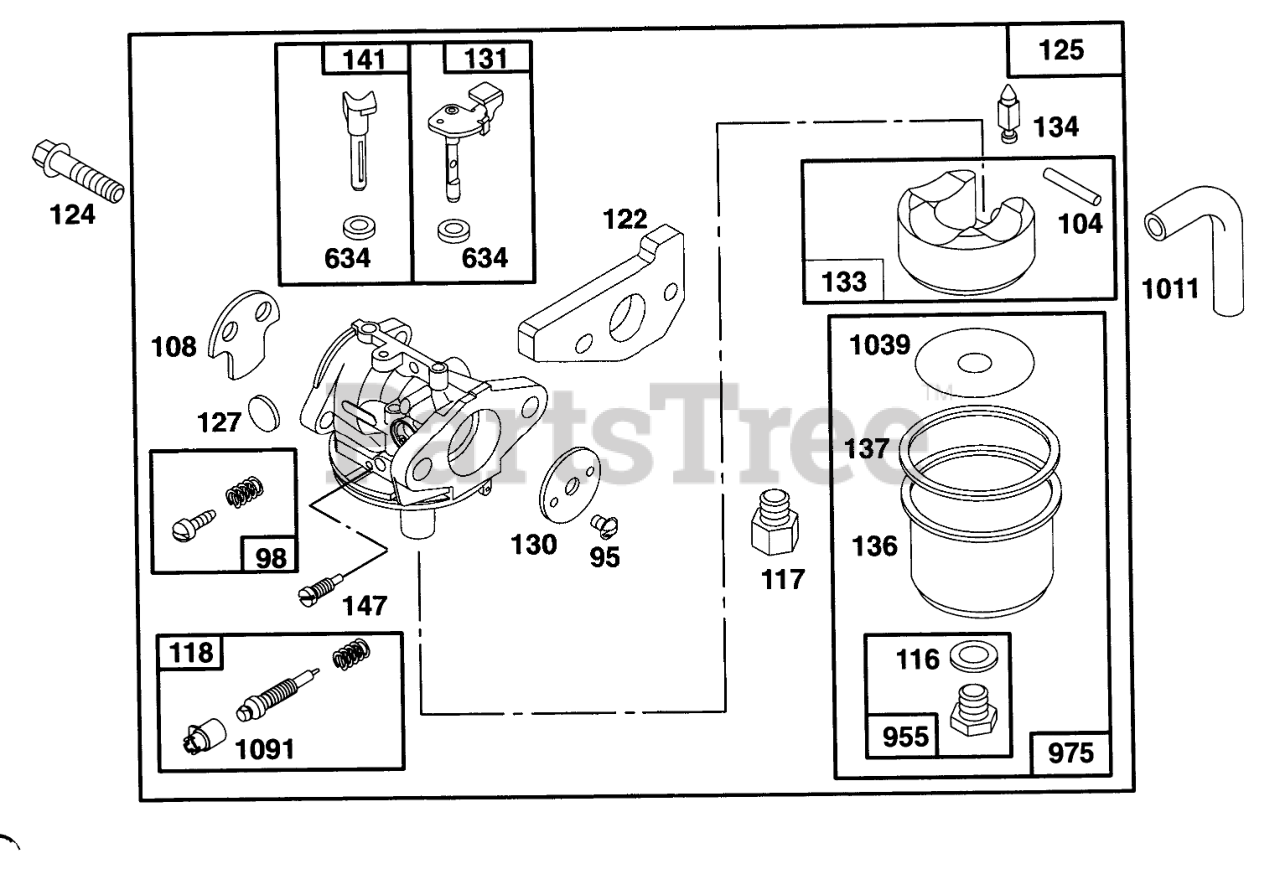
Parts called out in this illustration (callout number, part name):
95	SCREW - ROUND HEAD
98	IDLE ADJUSTING SCREW
104	FLOAT HINGE PIN
108	VALVE - CHOKE
116	SEALING GASKET
117	Jet-Main
118	VALVE/SPRING - NEEDLE
122	ADAPTER ASSEMBLY
124	HEX HEAD SCREW
125	ASSEMBLY - CARBURETOR
127	PLUG - WELCH
130	THROTTLE VALVE
131	THROTTLE SHAFT
133	FLOAT-CARBURETOR
134	Valve-Inlet (Includes Seat)
136	FLOAT BOWL
137	FLOAT BOWL GASKET
141	CHOKE SHAFT
147	JET - PILOT
634	SEAL WASHER
955	HEX HEAD SCREW
975	CARBURETOR BOWL ASM
1011	VENT TUBE
1039	FLOAT LIMITER
1091	CAP - LIMITER
